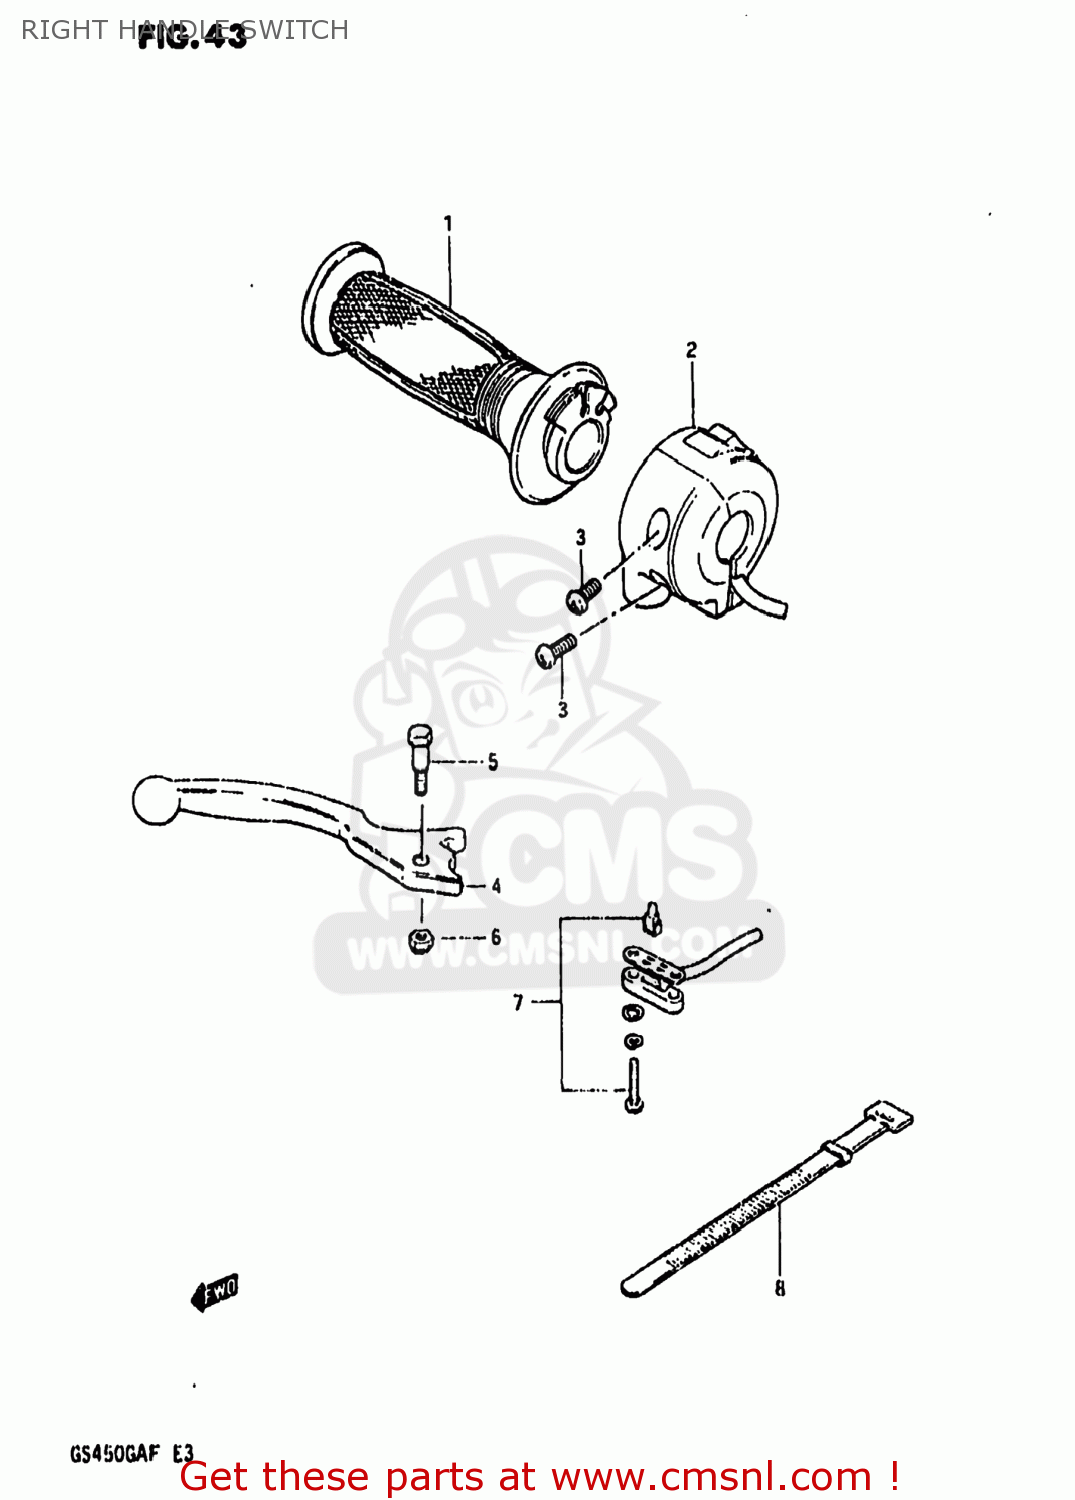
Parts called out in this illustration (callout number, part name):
1	GRIP,THROTTLE
2	SWITCH ASSY,HANDLE,R
3	SCREW
4	LEVER,BRAKE
5	BOLT,LEVER PIVOT
6	NUT
7	SWITCH ASSEMBLY
8	CLAMP(L:120)
